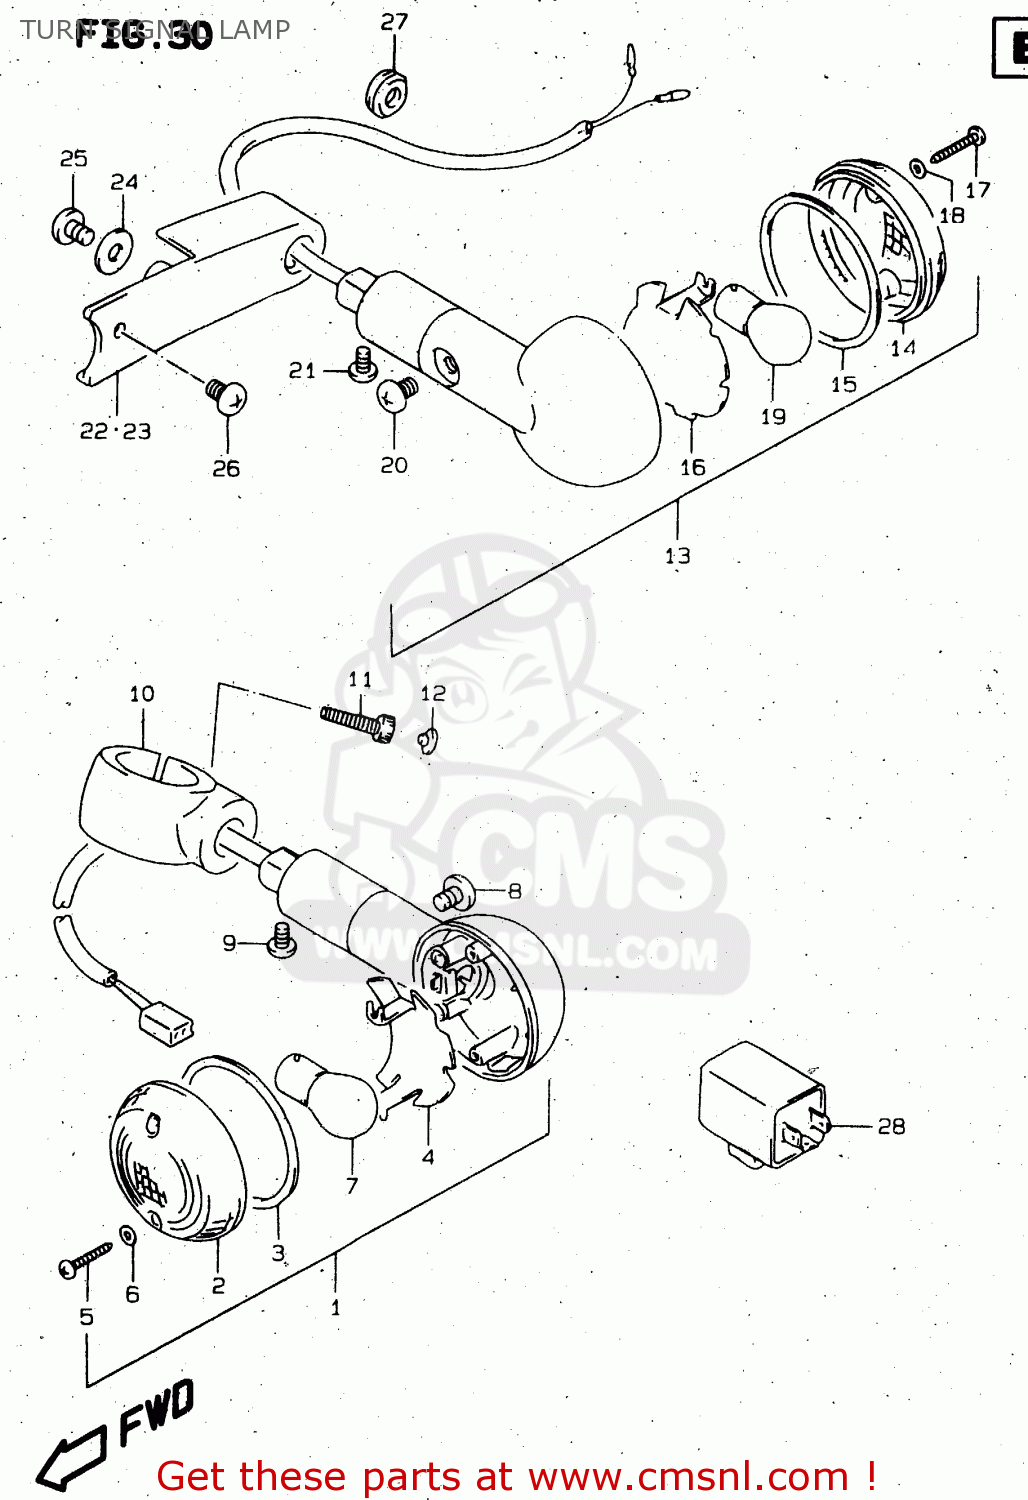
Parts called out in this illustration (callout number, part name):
1	LAMP ASSY,FR TURN SIGNAL,R
2	LENS
3	GASKET (NAS)
4	REFLECTOR
5	SCREW
6	GASKET (NAS)
7	BULB(12V21W)
8	SCREW
9	SCREW
10	BRACKET,FR TURNSIGNAL LAMP,R
11	BOLT
12	CAP(OD:10)
13	LAMP ASSY,RR TURNSIGNAL,R
14	LENS
15	GASKET (NAS)
16	REFLECTOR
17	SCREW
18	GASKET (NAS)
19	BULB(12V21W)
20	SCREW
21	SCREW
22	BRACKET,RR TURNSIGNAL LAMP,R
23	BRACKET,RR TURNSIGNAL LAMP,L
24	WASHER(6.5X20X1.6)
25	SCREW 6X12
26	SCREW 6X12
27	GROMMET
28	RELAY ASSY
